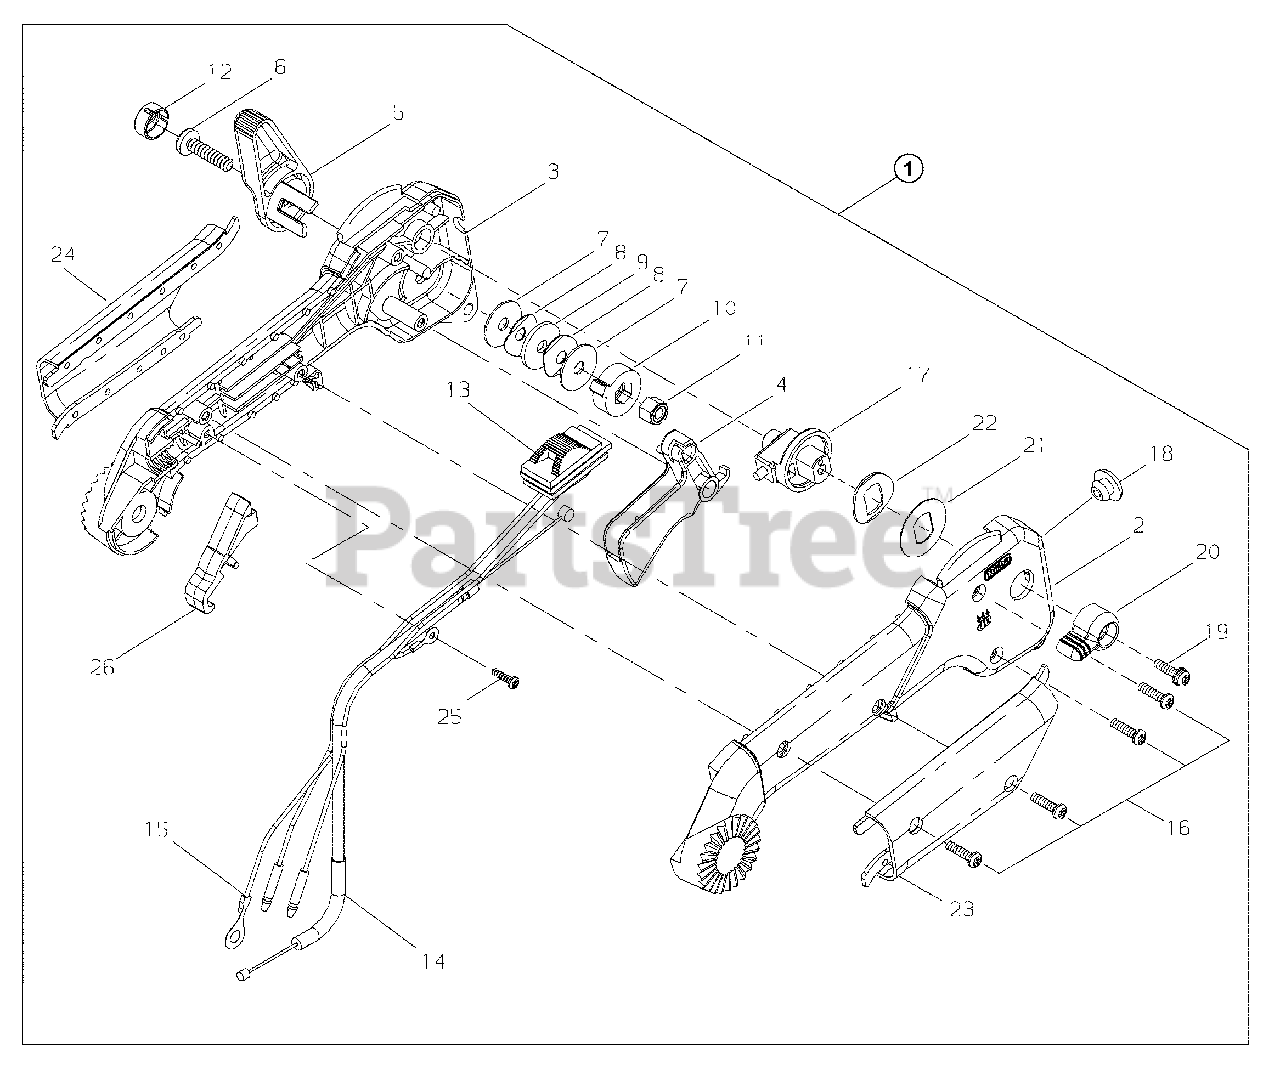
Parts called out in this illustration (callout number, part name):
1	THROTTLE LEVER ASSY
2	HANDLE, CONTROL - RIGHT
3	HANDLE, CONTROL - LEFT
4	TRIGGER, THROTTLE
5	LEVER, LOCK
6	ADJUSTABLE BOLT
7	WASHER - 6
8	LOCKWASHER
9	WASHER - 6
10	PLATE
11	NUT - 6 -- NYLON
12	CRUISE CONTROL BOLT CAP
13	SWITCH, IGNITION
14	CABLE, THROTTLE
15	LEAD - GROUND
16	SCREW
17	ADJUSTER ASSY
18	PLUG
19	SCREW, METERING LEVER PIN
20	SCREW, METERING LEVER PIN
21	WASHER
22	WASHER - SPRING
23	GRIP - RIGHT
24	GRIP - LEFT
25	SCREW - 3
26	COVER, HANDLE
